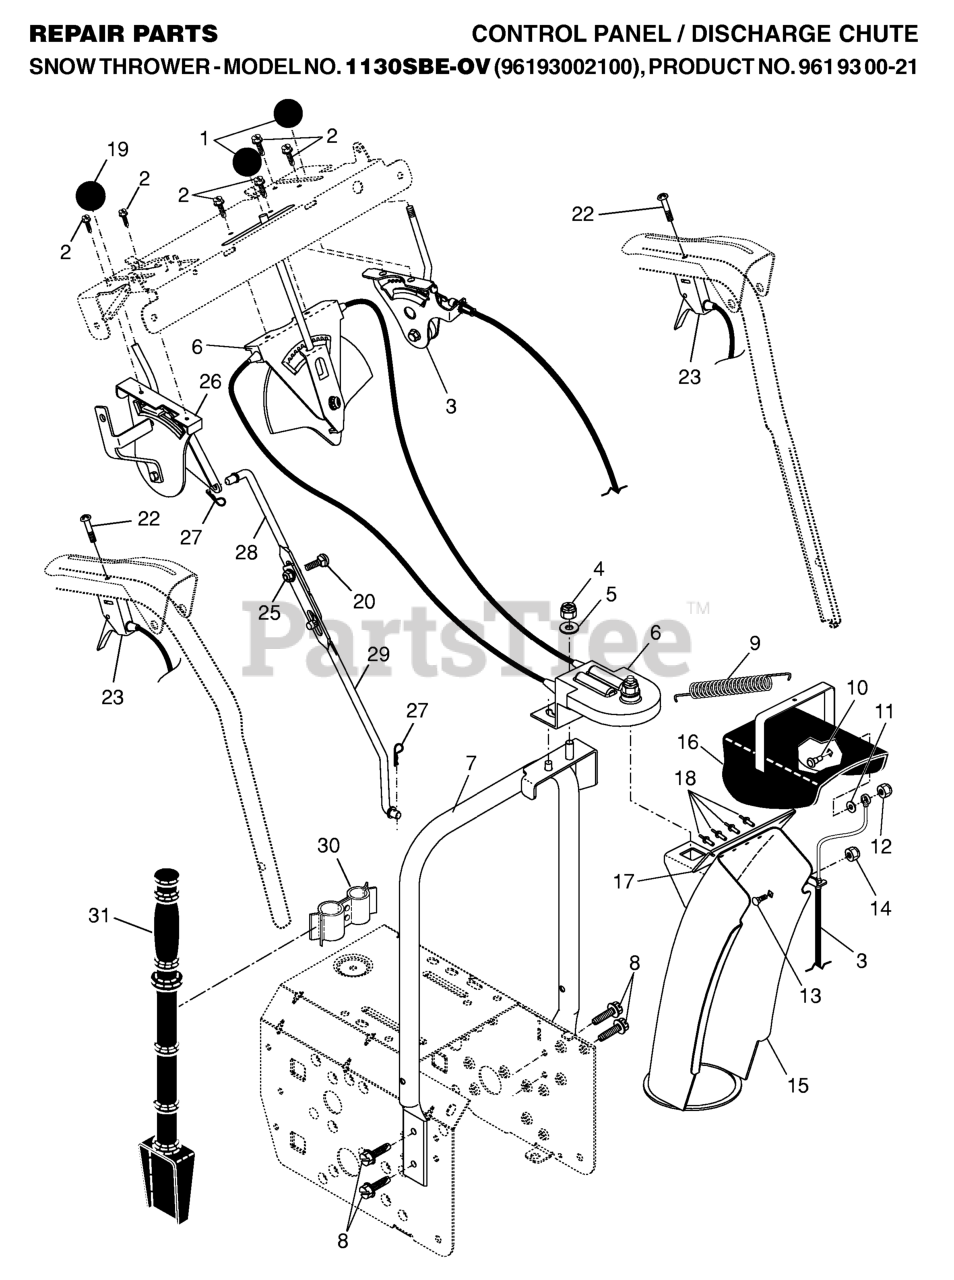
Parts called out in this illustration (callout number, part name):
1	KNOB, LEVER
2	SCREW #10-24 X 5/8
3	CONTROL.CABLE.DEFLECTOR
4	NUT
5	WASHER
6	CONTROL ASSEMBLY,CHUTE ROTATER
7	SUPPORT, PIVOT
8	SELF-TAPPING SCREW 5/16-18X3/4
9	SPRING.DEFLECTOR.REM.CHUTE
10	BOLT, SHOULDER
11	WASHER, NYLON FRICTION
12	NUT.HEX.FLANGE.1/4
13	BOLT
14	NUT.LOCK.5/16-18
15	CHUTE ASSEMBLY
16	DEFLECTOR.WELDMENT.PNT.ORANGE
17	SEAL, DEFLECTOR
18	RIVET BLIND
19	RP KNOB, SPEED CONTROL LEVER
20	BOLT, HEX HEAD
23	STEERING.CONTROL.SNOW.BLUE
25	NUT, HEX FLANGE 5/16-18
26	HEAD ASSY SPEED
27	SPRING RETAINER
28	ROD, UPPER SPEED CONTROL
29	ROD, LOWER SPEED CONTROL.SNOW
30	CLAMP.ASM.CLEANOUT.TOOL.SNOW
31	CLEAN OUT TOOL
